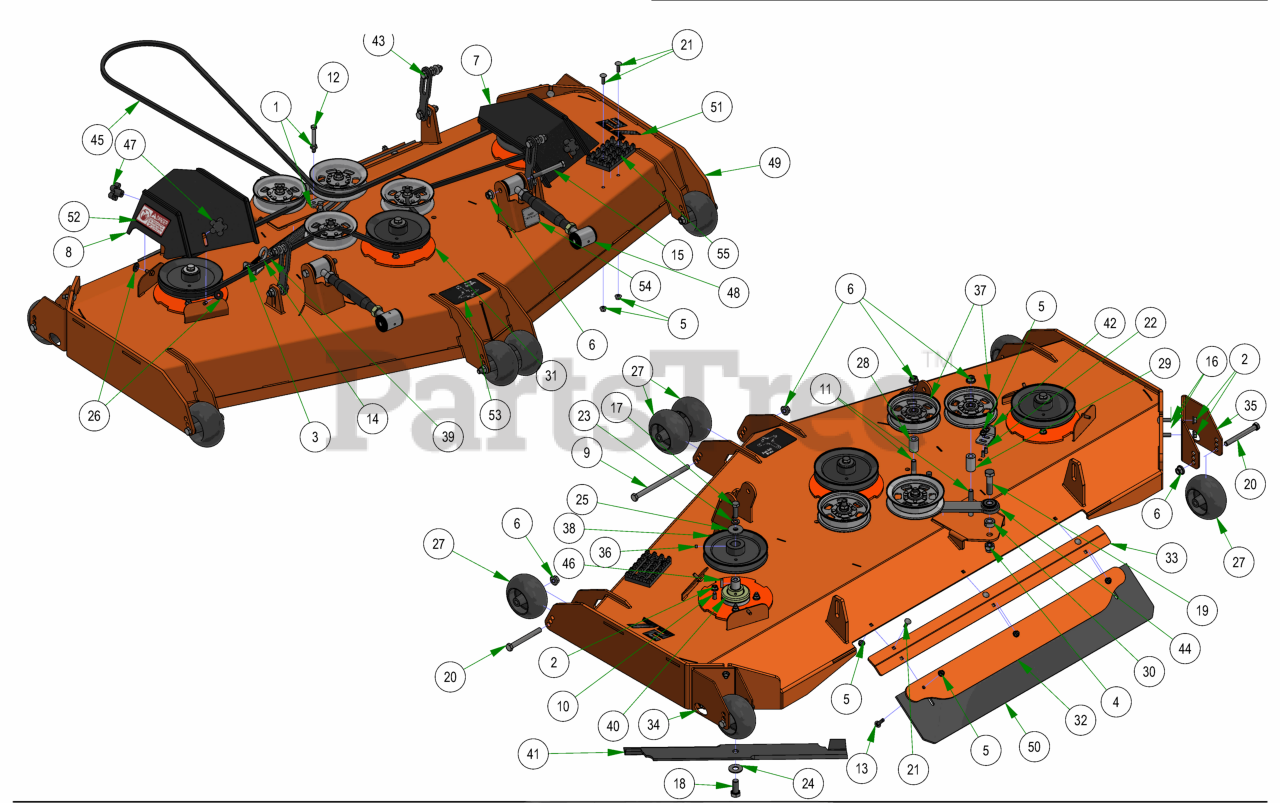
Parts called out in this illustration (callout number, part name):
1	3/8-16 HEX SERRATED FLANGE NUT HARD/ZINC
2	3/8-16 NYLON INSERT FLANGE LOCKNUT (GR.F) ZINC
3	3/8-16 HEX NUT ZINC
4	5/8-11 NYLON INSERT LOCKNUT ZINC
5	5/16-18 NYLON INSERT FLANGE LOCKNUT ZINC
6	1/2-13 NYLON INSERT FLANGE LOCKNUT ZINC
7	Pulley Cover LH Rebel, Rogue, Renegade 72"
8	Pulley Cover RH Rogue, Rebel, Renegade 72"
9	1/2-13 X 8 HEX CAP SCREW GR 5 ZINC
10	3/8-16 X 1-3/4 HEX C/S (GR.5) ZC
11	1/2-13 X 3-1/2 HEX FLANGE BOLT (GR.8) ZINC
12	3/8-16 X 3 HEX CAP SCREW (GR.5) ZINC
13	5/16-18 X 1-1/4 CARRIAGE BOLT ZINC
14	4" 3/8-16 Eye Bolt
15	1/2-13 X 4 HEX CAP SCREW (GR.8) ZINC YELLOW
16	3/8-16 X 1-1/4 CARRIAGE BOLT ZINC
17	1/2-20 X 1-1/2 HEX CAP SCREW (GR.5) ZINC
18	5/8-18 X 1-1/2 HEX CAP SCREW (GR.8) ZINC YELLOW
19	5/8-11 X 2-1/2 HEX CAP SCREW (GR.5) ZINC
20	1/2-13 X 4-1/2 HEX CAP SCREW (GR.5) ZINC
21	5/16-18 X 1 CARRIAGE BOLT (GR.8) ZINC
22	5/16-18 X 7/8 CARRIAGE BOLT ZINC
23	1/2 SPLIT LOCKWASHER (GR.8) ZINC/YELLOW
24	5/8 USS FLAT WASHER (1-3/4" OD) GR.8 ZINC YELLOW
25	1/2 BELLEVILLE WASHER (1-5/8 OD X .140 THK) ZINC
26	.360 ID X .983 OD X .120 THICK FLAT WASHER NYLON BLACK
27	2019 Deck Wheel
28	.502 ID X .750 OD X 1.500 Long Spacer
29	1 3/4" Pulley Spacer
30	5/8 SOLID SHAFT COLLAR (W/1 SET SCREW) ZINC
31	Deck Spindle Support Plate
32	61 Bolt in Baffle Deck v2 Stripping Plate
33	Rubber Mount Plate - Rear Discharge
34	LH Rear Deck Wheel Bracket - Rear Discharge
35	RH Rear Deck Wheel Bracket - Rear Discharge
36	5/16-24 X 1/4 SOCKET SET SCREW (CUP PT) PLAIN
37	5-3/4 Idler Pulley
38	7" Deck Pulley
39	2019 Outlaw Gen2 Deck Spring
40	OUTLAW SPINDLE ASSEMBLY
41	72" High Lift Fusion Blade
42	2019 Deck Eye Bolt Tab
43	Deck Hanger Assembly
44	2019 Rebel Rogue Deck Idler
45	B202 Belt for 72" Outlaw
46	1/4 X 1 SQ MACHINERY KEY 1018 STL PLN
47	5/16" Knob
48	Turnbuckle Assembly (M20-2.5)
49	72 Rear Discharge Deck
50	R Series Rubber For Deck
51	72" Deck Decal
52	Danger Decal-Spindle/Discharge
53	2019 Rebel & Rogue Deck Belt Route Decal
54	Deck Impact Patent Decal 9591803
55	Deck Step Assembly
